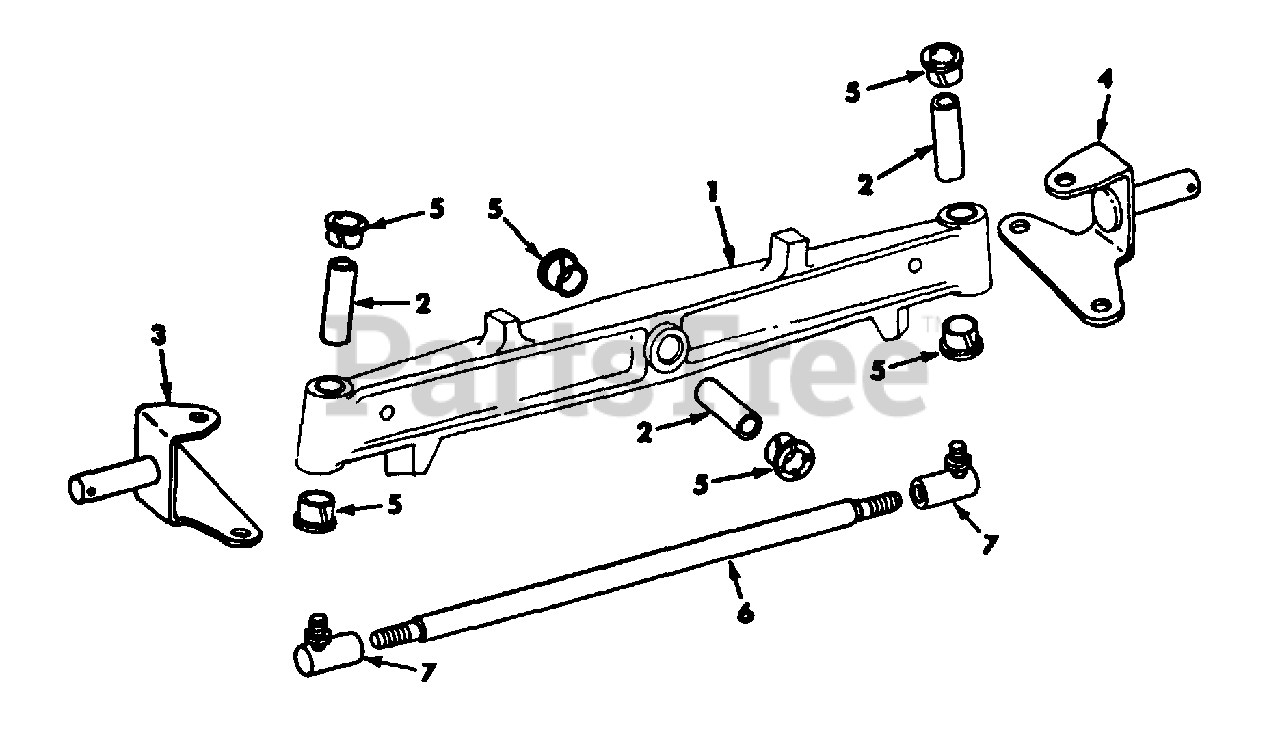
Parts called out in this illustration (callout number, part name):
1	AXLE, FRONT
2	BUSHING, FRONT AXLE
3	ARM ASSY, SPINDLE RH
4	ARM ASSY, SPINDLE LH
5	BEARING, FRONT AXLE
7	JOINT, TIE ROD
